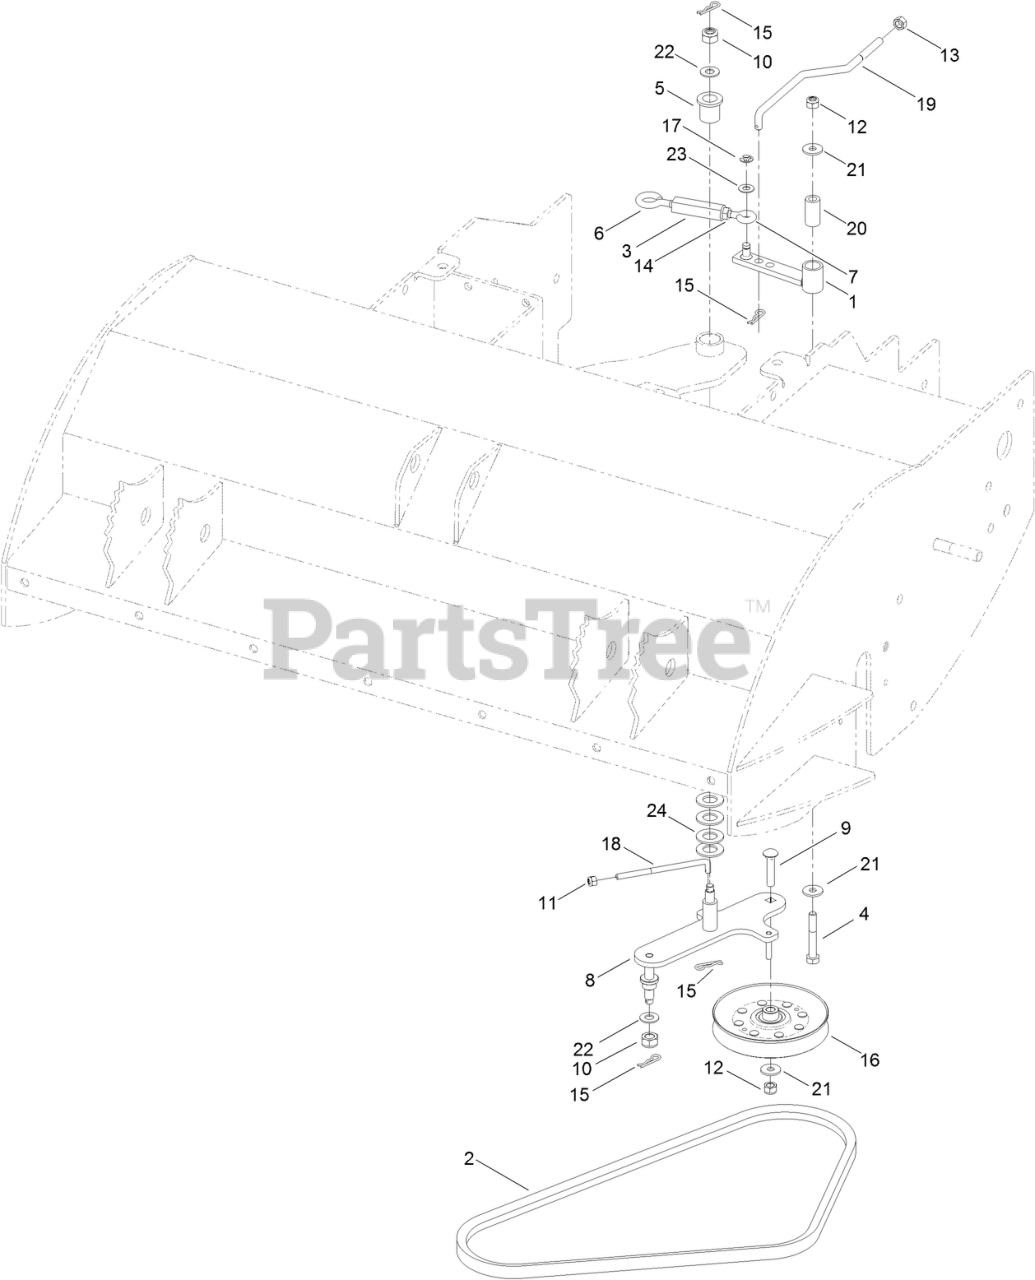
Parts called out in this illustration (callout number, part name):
1	ARM-ASSIST
2	BELT-V
3	BODY-TURNBUCKLE
4	SCREW-HH
5	BUSHING-FLANGE, OILITE
6	EYEBOLT-THREAD, LH
7	EYEBOLT-THREAD, RH
8	IDLER-CLUTCH
9	BOLT-COACH
10	NUT-HEX, NI
11	NUT-NYLOC
12	NUT-HEX, NI
14	NUT-HF
15	PIN-COTTER
16	PULLEY-IDLER CLUTCH
17	RING-RETAINING, EXT
18	ROD-BRAKE
19	ROD-LINKAGE, DRIVE
20	TUBE-PIVOT
21	WASHER
22	WASHER-PLAIN
23	WASHER
24	WASHER-PLAIN
